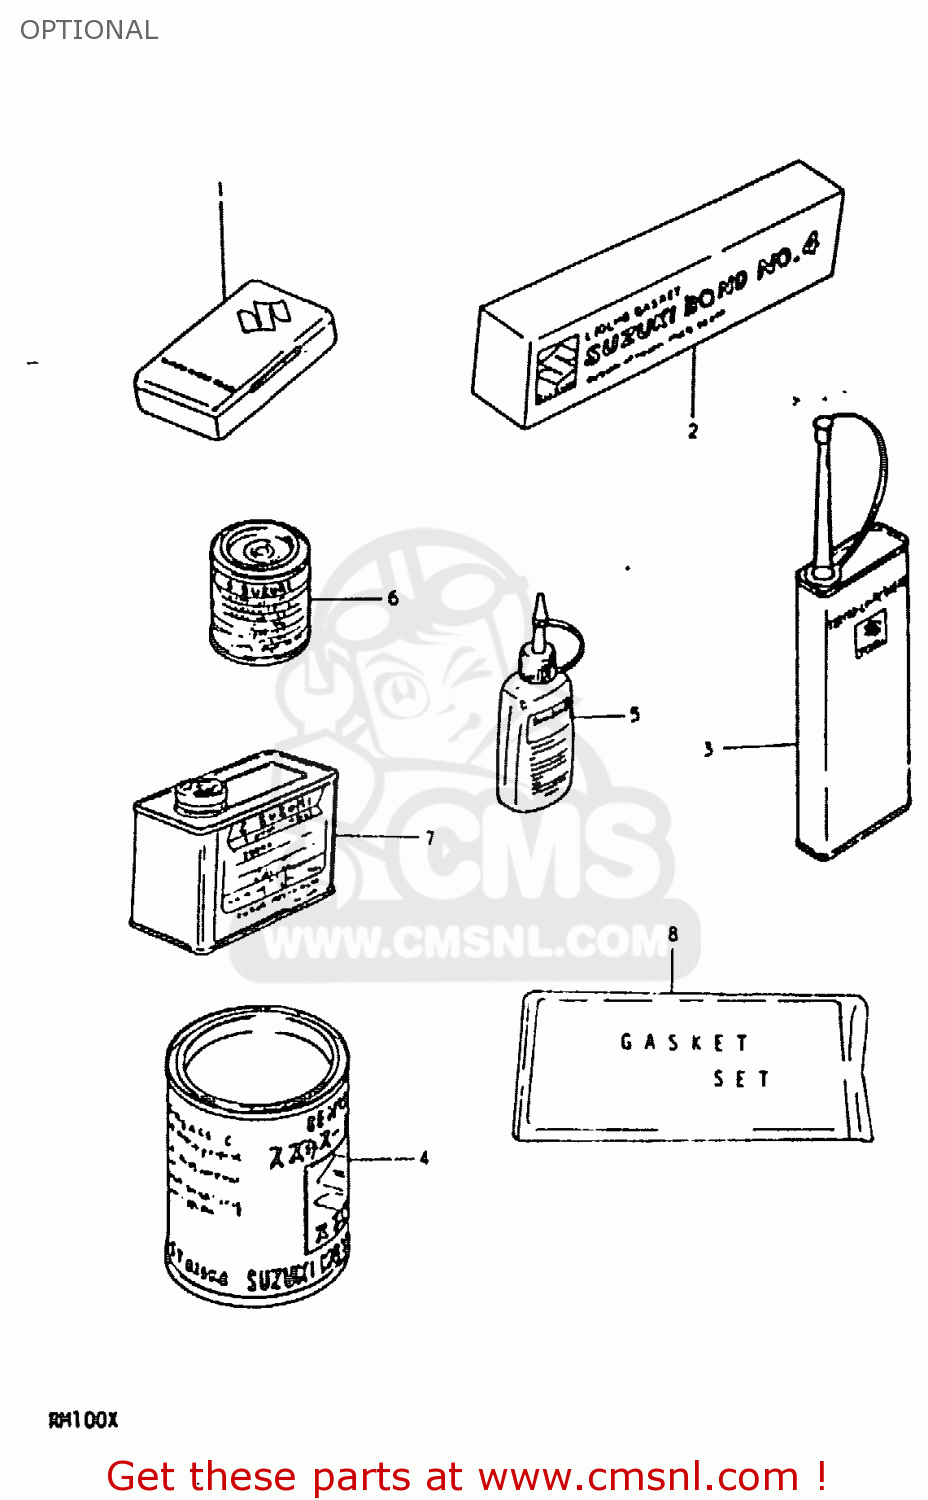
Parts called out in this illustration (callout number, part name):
1	TUBE REPARING TOOL
2	BOND 1104
3	THREAD LOCK NO.1401 CLEAR 200G
4	GREASE(C)EP2 LITHIUM 150G
5	THREAD LOCK NO.1342
6	PAINT,BLACK
7	PAINT (BLACK)
8	GASKET SET (MCA)
